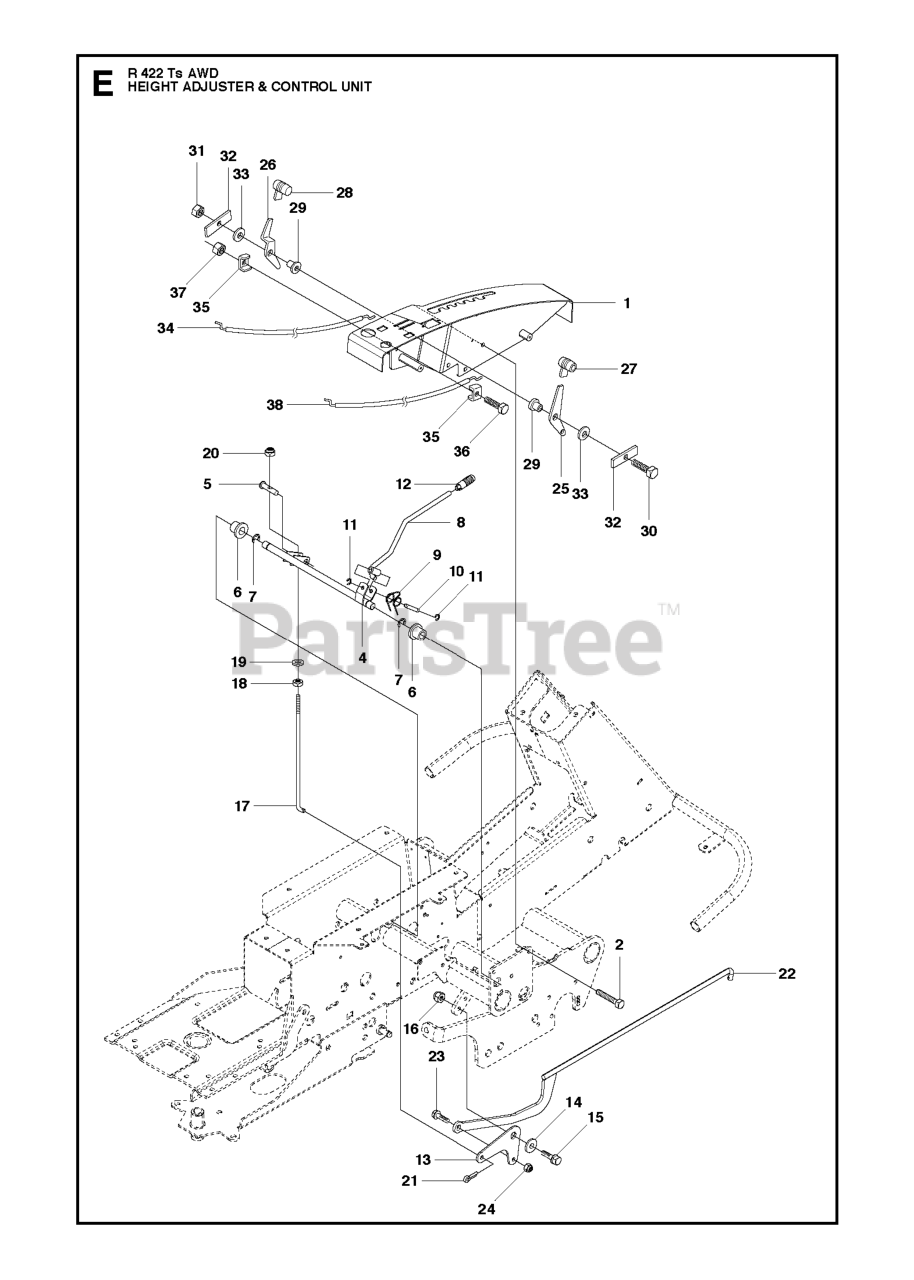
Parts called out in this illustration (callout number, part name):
6	BUSHING
9	HAIR PIN SPRING
12	GEAR STICK KNOB
14	WASHER
16	LOCKNUT M6
18	NUT
19	WASHER
20	LOCKNUT M8
24	NUT
30	SCREW M6S 6X30
31	LOCKNUT M6
33	SPRINGWASHER
37	LOCKNUT M5
